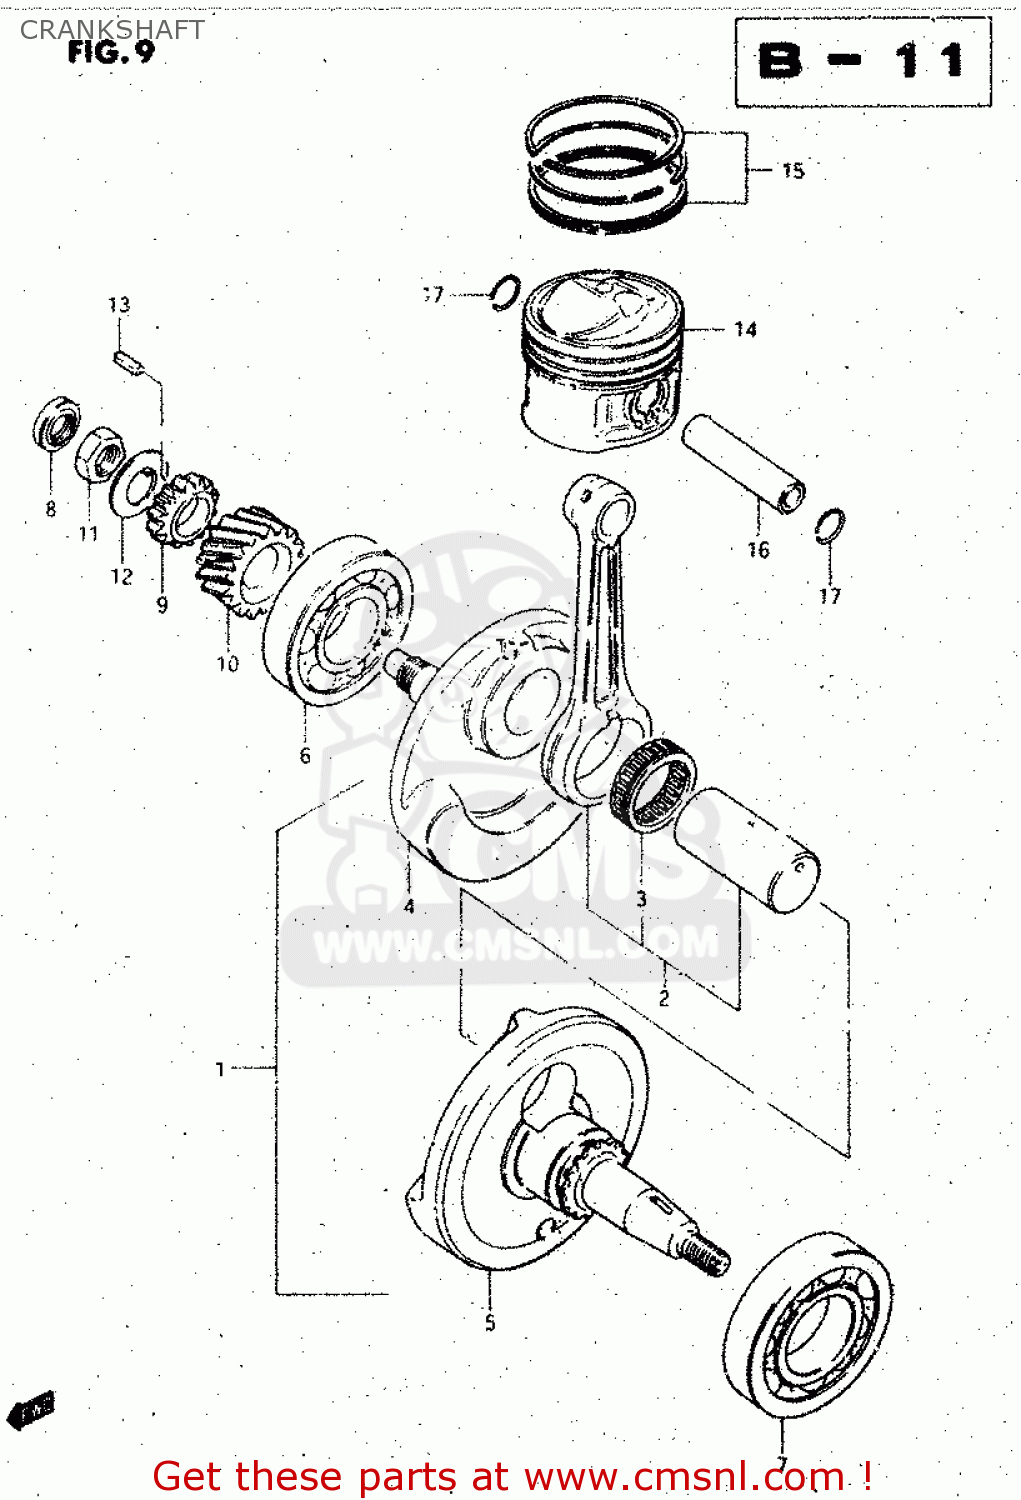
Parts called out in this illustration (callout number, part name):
1	CRANKSHAFT ASSEMBLY
2	CONNECTING ROD SET
3	BEARING(28X36X15.8)
4	CRANKSHAFT,RIGHT
5	CRANKSHAFT,L
6	BEARING(28X68X18)
7	BEARING(35X72X17)
8	SEAL,OIL(12X21X7)
9	GEAR,OIL PUMP DRIVE
10	GEAR,PRIMARY DRIVE
11	NUT
12	WASHER
13	KEY
14	PISTON (STD)
15	RING SET,PISTON
16	PIN,PISTON
17	RING,SNAP 14MM
